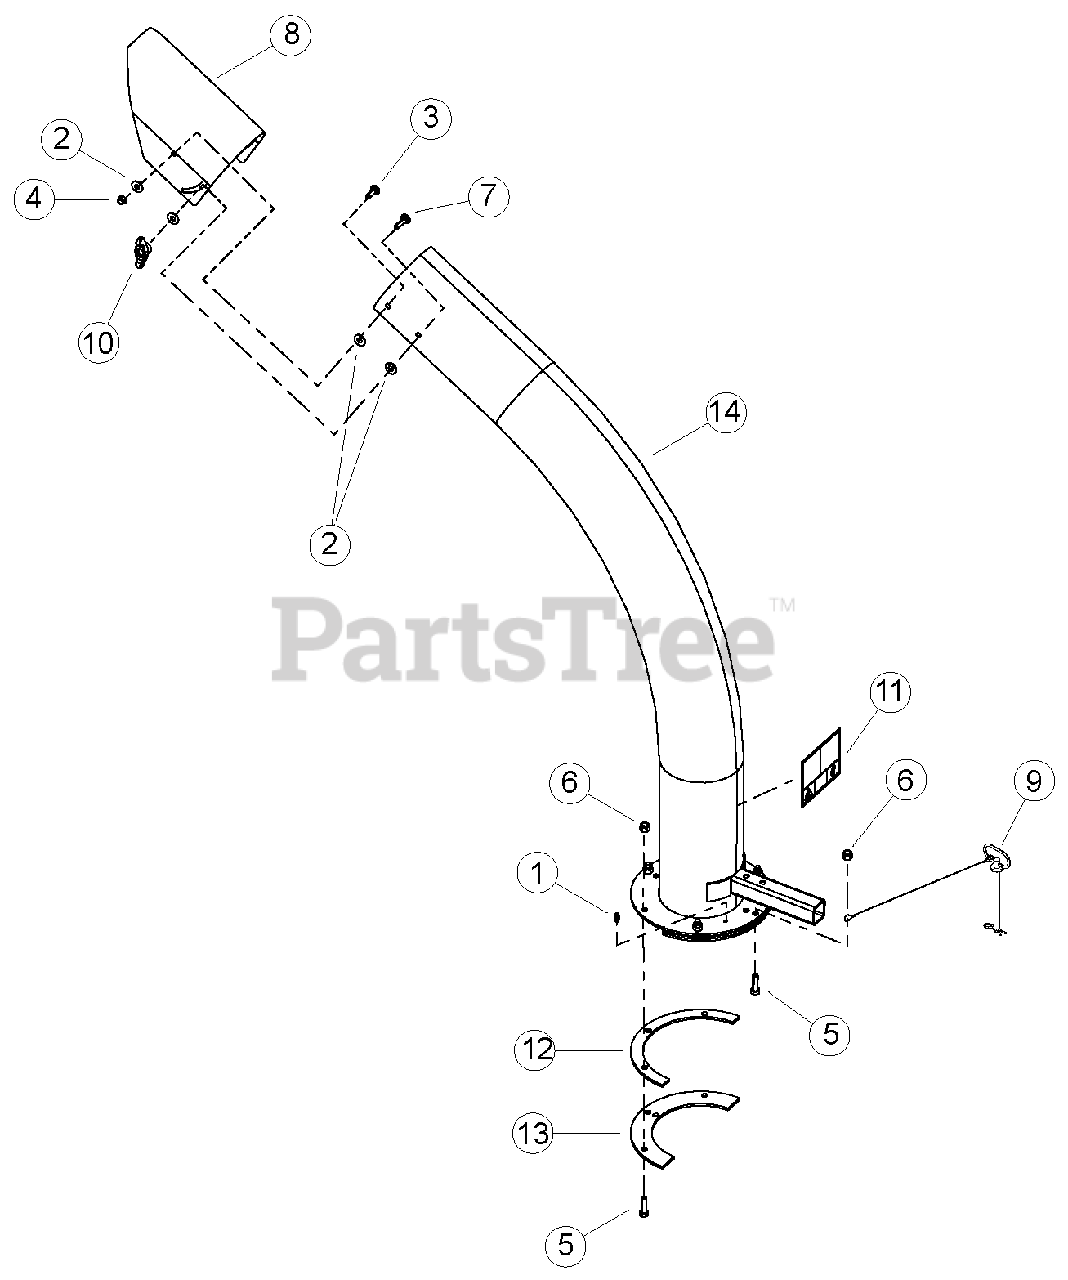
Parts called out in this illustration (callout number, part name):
1	FITTING, 1/4 SELF-TAP GREASE
2	WASHER, 5/16 FLAT ZP
3	BOLT, 5/16 X 1 CRG GR5 ZP
4	NUT, 5/16 NE NYLOCK ZP
5	BOLT, 3/8 X 1-1/4 HEX HD GR5 ZP
6	NUT, 3/8 NE NYLOCK ZP
7	BOLT, 5/16 X 1-1/4 CRG GR5 ZP
8	DEFLECTOR, BLOWER-VAC DISCHARGE
9	PIN, 3/8" X 4.25" DISCHARGE
10	KNOB, 5/16-18 UNC TEE W/LOCKING INSERT
11	DECAL, DISCHARGE DEBRIS & LOCK
12	SPACER, DISCHARGE PIVOT
13	RING, DISCHARGE CLAMP
14	ASSEMBLY, 8 INCH DISCHARGE CHUTE
